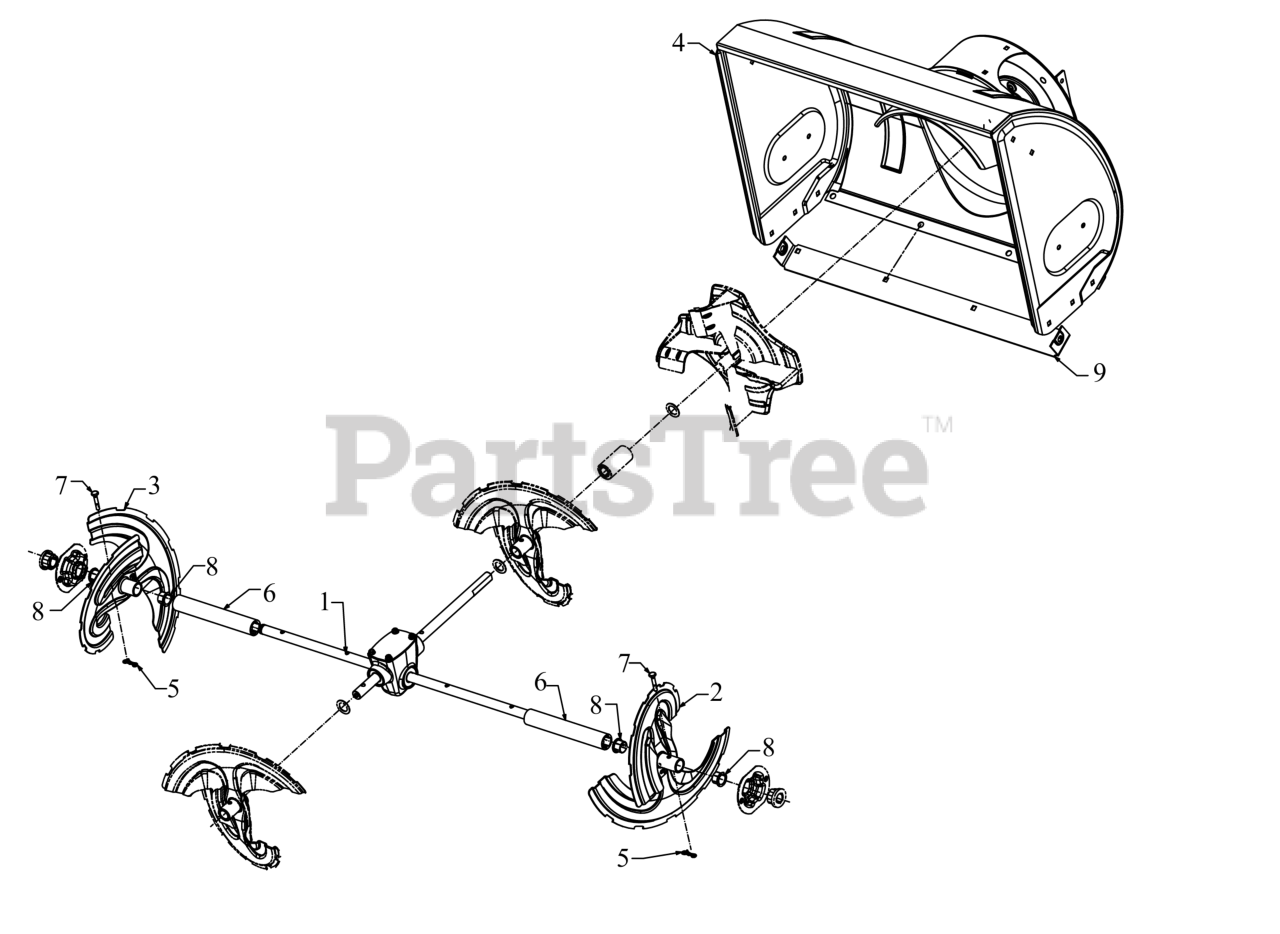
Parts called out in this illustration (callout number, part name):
1	28" AUGER GEARBOX ASSEMBLY
5	BOW TIE COTTER PIN 1/4-5/16
6	SPACER
7	SHEAR PIN .25 x 1.50 GR2
8	FLANGE BUSHING
